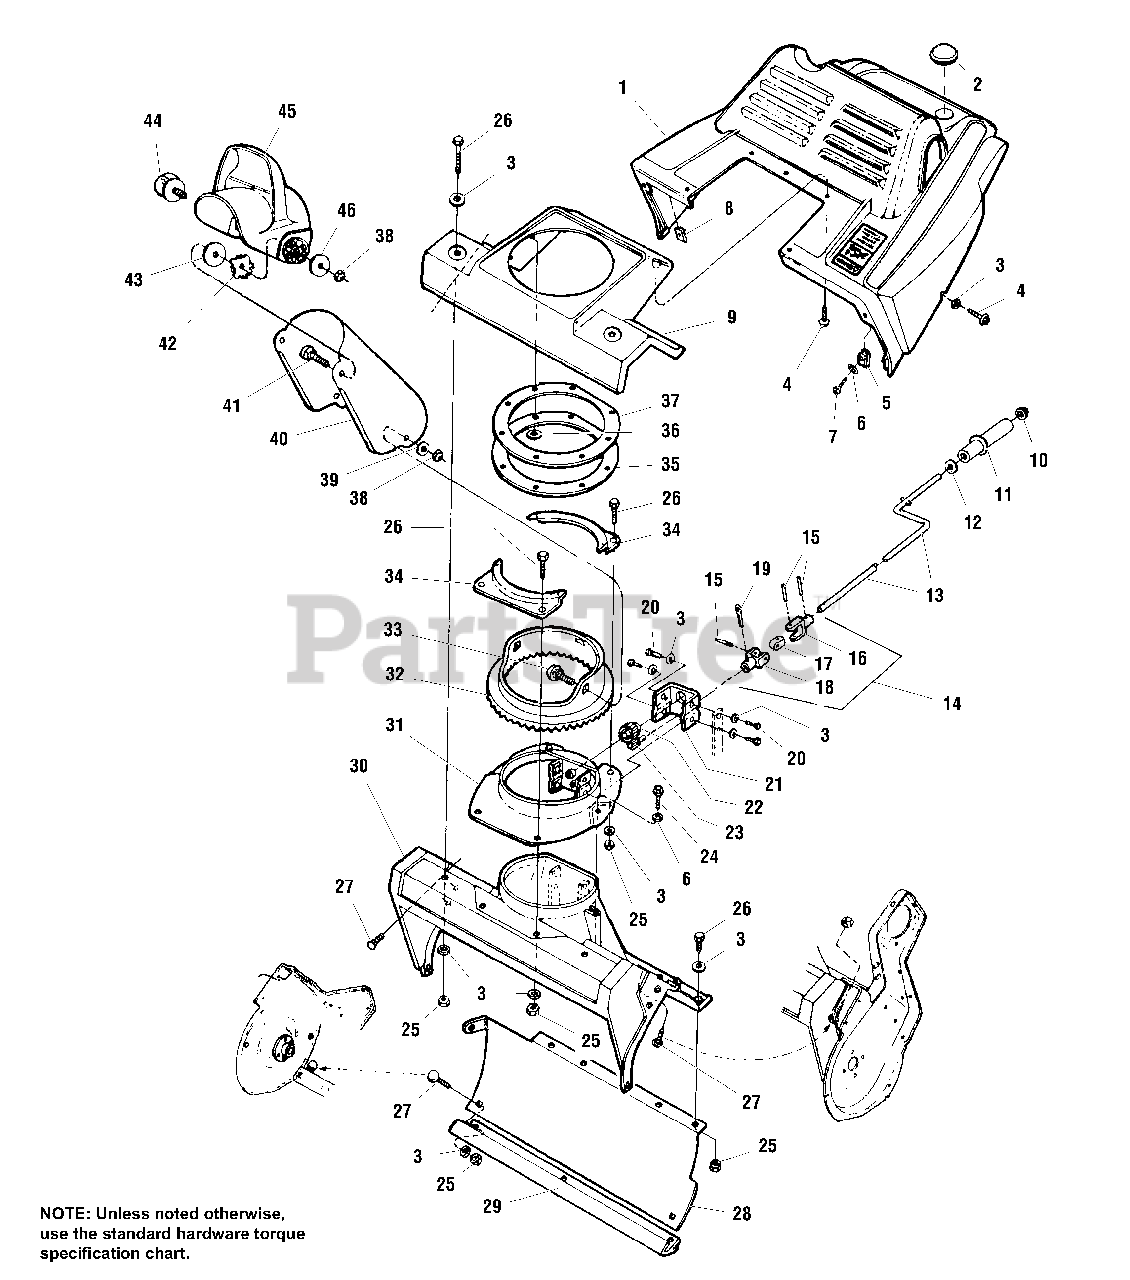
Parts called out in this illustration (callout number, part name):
1	COVER, Engine
2	PLUG, Snap-in
3	WASHER, Flat, 1/4
4	SCREW, Plastite .225 x .75
5	CLIP, #10
6	WASHER, Flat #10
7	SCREW, Hex, #10-16 x 1-1/2
9	COWLING, Transition
10	CAP, Push
11	KNOB, Chute Rotating
12	WASHER, Flat, 5/16
13	HANDLE, Chute Rotate
14	ASSEMBLY, U-Joint
15	PIN, Spiral, 5/32 x 1
16	CLEVIS, Rear U-Joint
17	CONNECTOR, U-joint
18	CLEVIS, U-Joint
19	PIN, Cotter, 1/8 Dia.
20	SCREW, Hex, 1/4 - 20 x 5/8
21	BRACKET, Gear
22	GEAR, Idler
23	DRIVE, Gear
24	SCREW, Plastite, #12-14 x 1
25	NUT, Nylock, 1/4-20
26	SCREW, Hex, 1/4-20 x 3/4
27	CARRIAGE BOLT, 1/4-20 x 3/4
29	SCRAPER, Bar
30	HOUSING, Auger
31	PLATE, Chute Base
32	BASE, Chute
33	CARRIAGE BOLT, 5/16-18 x 5/8
35	RETAINER, Gasket
36	NUT, Push On
37	GASKET, Chute
38	NUT, Nylock, 5/16-18
39	WASHER, Flat
40	CHUTE, Discharge
41	CARRIAGE BOLT, 5/16-18 x 1
42	WASHER, Octagon
43	WASHER, Flat Rubber
44	ASSEMBLY, Knob
45	DEFLECTOR, Chute
46	WASHER, Flat 5/16
